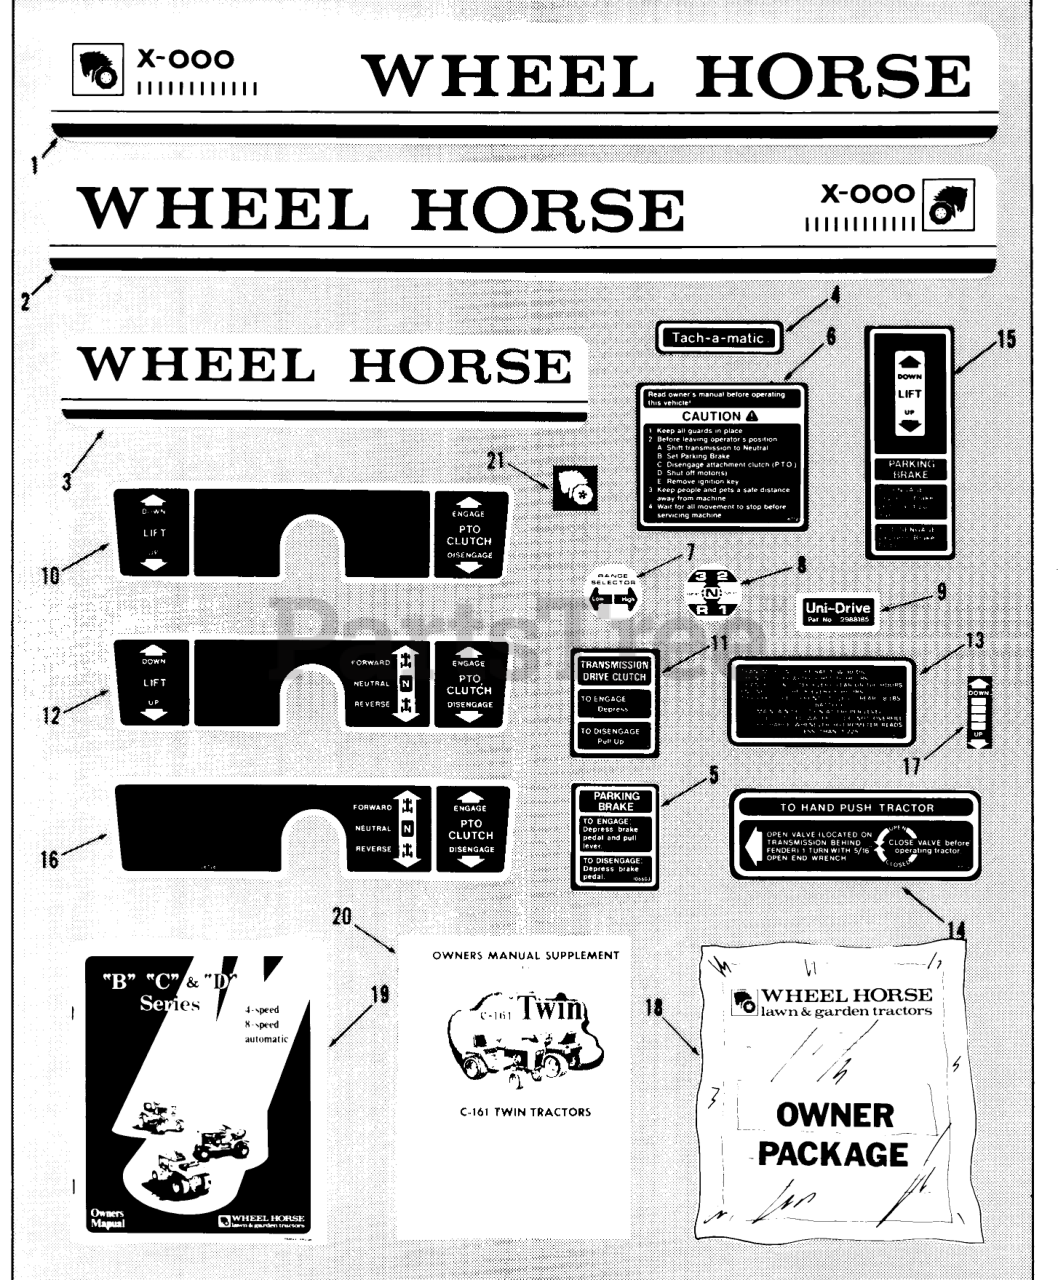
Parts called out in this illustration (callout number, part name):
2	Decal RH C-161 Automatic
2	ORDER 101637 R&L DECAL
2	Speed Nut
5	DECAL-PARKING BRAKE
9	Decal-Uni Drive
10	Decal-Control Housing
12	Decal-Control Housing C-121 Only
15	Decal-Parking Brake Lift
18	Loose Parts Package C-121, C-101 Only
18	Loose Parts Package C-161, C-141 Only
18	Loose Parts Package C-161 Twin Only
18	Loose Parts Package C-81 Only
19	Owner-s Manual
20	81-16B801/91-16B802REV1
21	DECAL-LOGO
